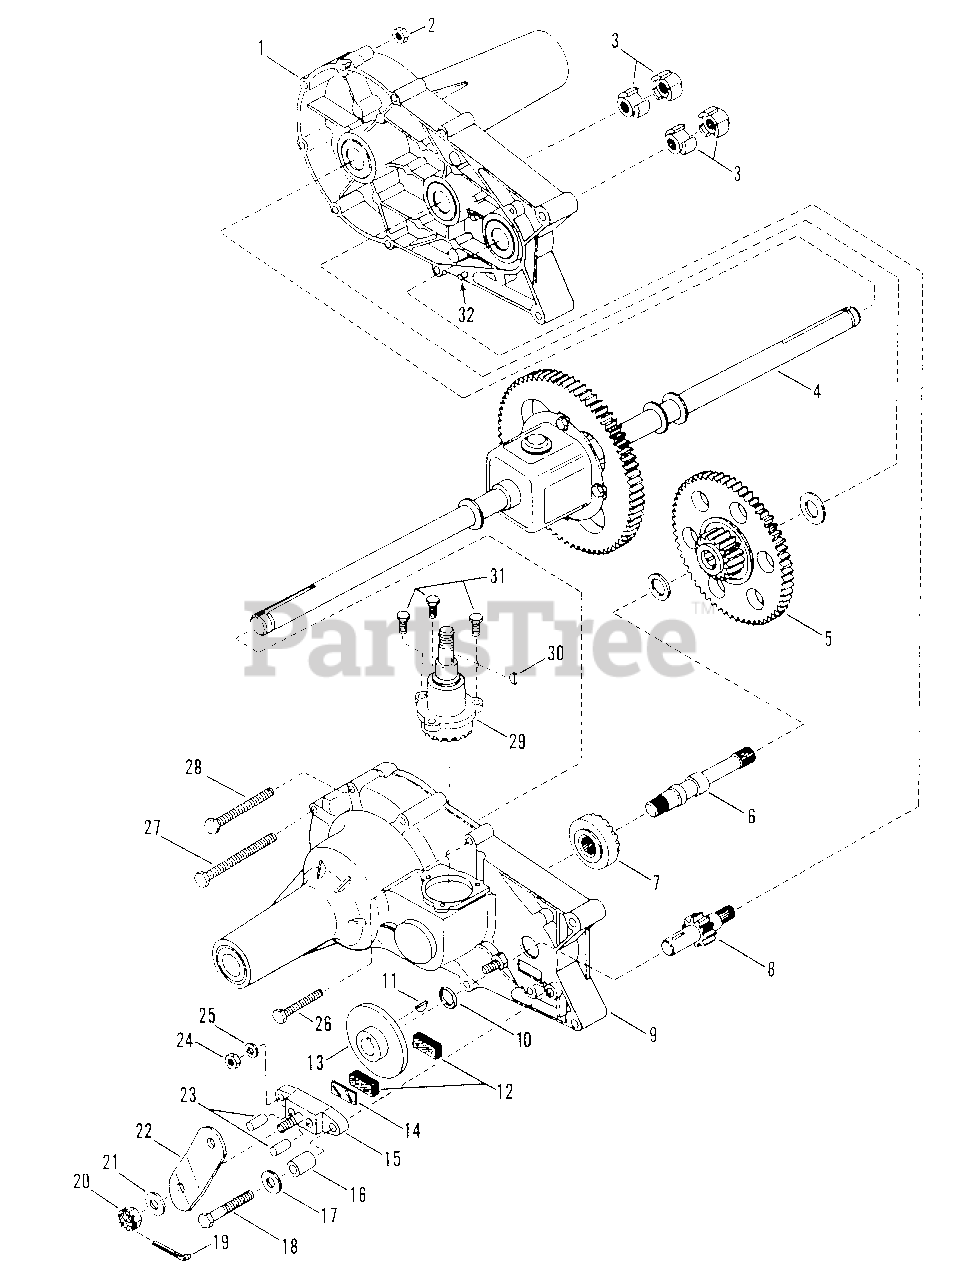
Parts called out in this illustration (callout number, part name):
1	ASSEMBLY, Transaxle Housing (Left Hand)
2	NUT, 5/16-18 Hex
3	COUPLING Pump
4	ASSEMBLY, Differential
5	ASSEMBLY, Reduction Gear
6	SHAFT, Drive
7	GEAR, Drive Pinion
8	SHAFT, Pinion Gear
9	ASSEMBLY, Transaxle Housing (Right Hand)
10	SEAL, Grease
11	KEY, 3/16 x 5/8" Hi-Pro
12	PUCK, Brake
13	DISC, Brake
14	PLATE, Puck
15	ASSEMBLY, Brake Yoke
17	WASHER, 9/32 I.D. x 7/8" O.D. Flat
18	BOLT, 1/4-20 x 2" Hex
19	PIN, Cotter
20	NUT, 5/16-24 Castle
21	WASHER, 11/32 I.D. x 7/8" O.D.Flat
22	ARM, Brake Actuator
23	PIN, Brake Actuating
24	NUT, 1/4-20 Hex
25	WASHER, 1/4 Spring Lock
26	BOLT, 1/4-20 x 2" Self-Tapping
27	BOLT, 5/16-18 x 3 3/4" Hex Head
28	BOLT, 1/4-20 x 3" Self-Tapping
29	ASSEMBLY, Input Pinion Housing
30	KEY, 3/32 x 5/8" Hi-Pro
31	SCREW, 1/4-20 x 3/4" Hex Head
32	PIN, Roll, 3/16 x 1.5"
